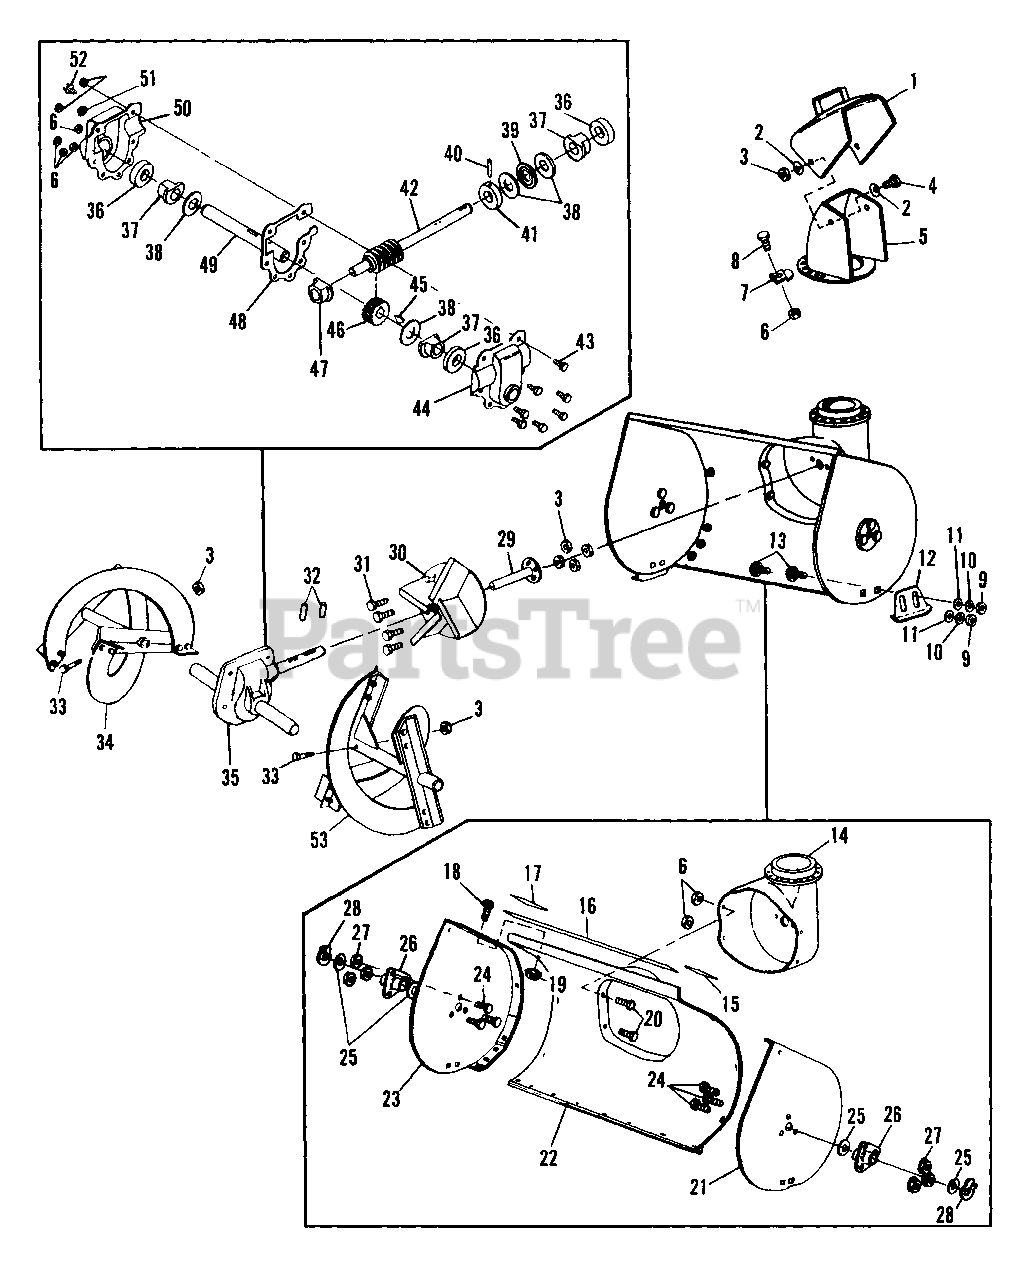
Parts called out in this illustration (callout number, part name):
1	DEFLECTOR ASSEMBLY
2	SPRING WASHER
3	NUT, Hex Centerlock, 5/16-18
4	CAPSCREW, Hex Head, 5/16-18 x 5/8
5	CHUTE ASSEMBLY
6	NUT, Hex Centerlock,1/4-20
7	CHUTE CLIP
8	CAPSCREW, Hex Head,1/4-20 x 1/2
9	NUT, Hex 3/8-16
10	LOCKWASHER,3/8
11	FLATWASHER, 5/16
13	CARRIAGE BOLT, 3/8-16 x 3/4
14	IMPELLER HOUSING ASSEMBLY
15	DECAL, Warning-Housing
16	DECAL, Simplicity 555
17	DECAL, Warning-Chute
18	CARRIAGE BOLT, 1/4-20 x 5/8
19	NUT, Hex Flange Lock, 1/4-20
20	CAPSCREW, Hex Head, 1/4-20 x 1/2
21	AUGER HOUSING END, LH
22	AUGER HOUSING & SCRAPER ASSEMBLY
23	AUGER HOUSING END, RH
24	CAPSCREW, Hex Head5/16-18 x 3/4
26	BEARING, Auger
27	NUT, Hex Flange Lock, 5/16-18
28	RETAINING RING
29	IMPELLER SHAFT ASSEMBLY
30	IMPELLER ASSEMBLY
31	CAPSCREW, Hex Head, 5/16-18 x 3/4
32	PIN, Roll
33	SHEAR BOLT KIT (Includes Ref. No. 3, Qty.-2)
34	AUGER ASSEMBLY, RH
37	FLANGE BEARING
38	THRUST COLLAR
39	NEEDLE BEARING
40	PIN, Roll .187 x 1.250
41	THRUST COLLAR
42	INPUT SHAFT
43	CAPSCREW,Hex Hd. .250-20 x .750
44	GEAR CASE - LH
45	KEY, Woodruff .188 x .625
46	WORM GEAR
47	FLANGE BEARING
48	GASKET - Gear Case
49	AUGER SHAFT
50	GEAR CASE - RH
51	NUT, Hex Keps .250-20
52	SCREW, Hex Hd. Taptite .375-16 x .500
53	AUGER ASSY - LH
